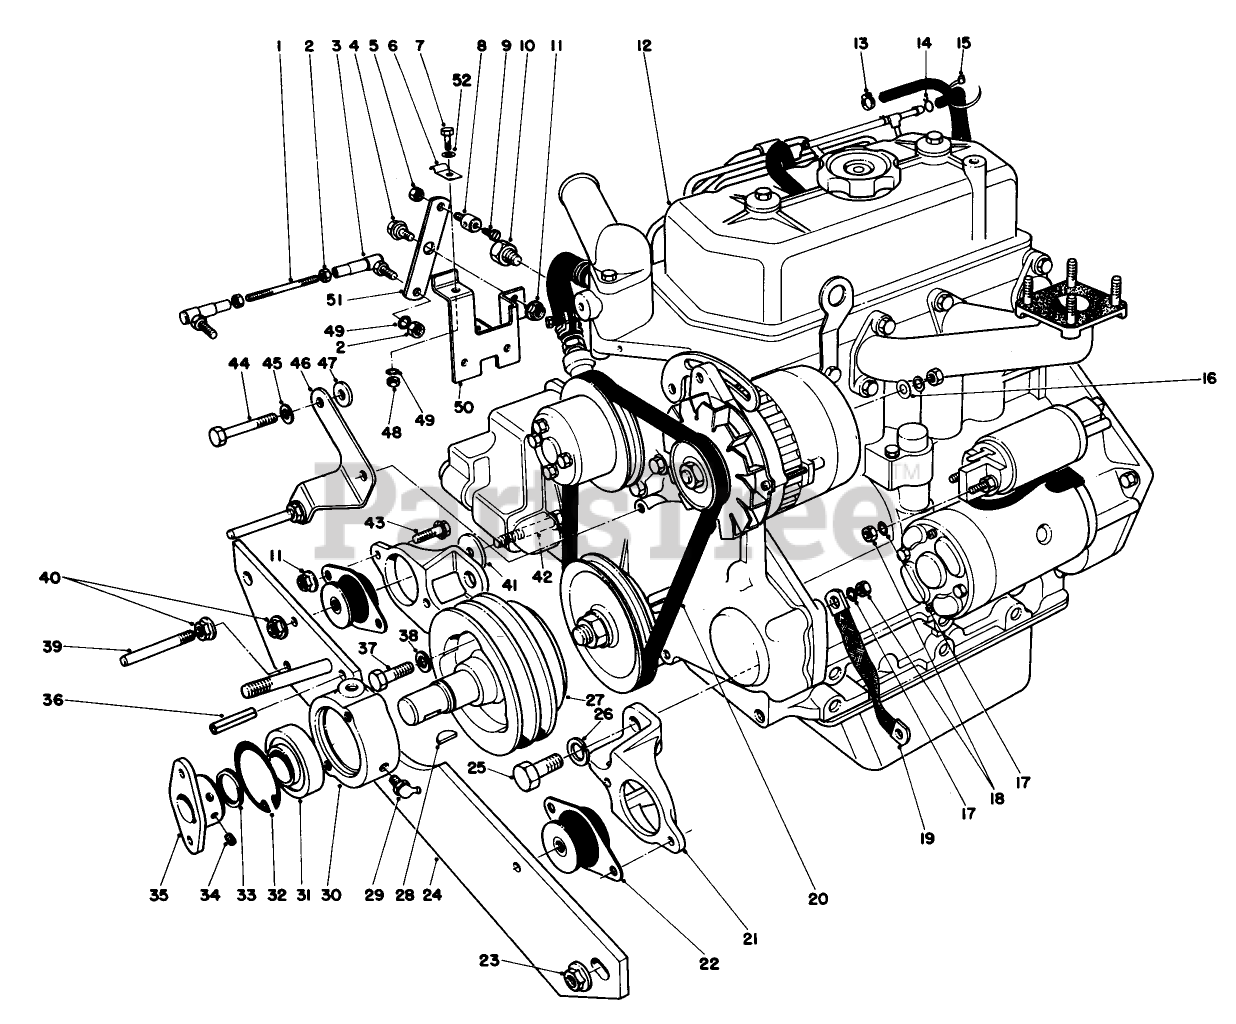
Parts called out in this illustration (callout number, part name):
1	THROTTLE LINK
2	NUT-HEX
3	BALL JOINT
4	BOLT-SHOULDER
5	NUT-LOCK, NI
6	CLAMP-BODEN
7	SCREW-HH
8	SWIVEL - CABLE
9	SCREW-HH
10	TEMP GAUGE ADAPTER
11	NUT-HF
12	Engine
13	CLAMP-HOSE
14	CLAMP-HOSE
15	TIE-CABLE
16	SPACER
17	WASHER-LOCK, INTERNAL
18	NUT-HEX
19	CABLE-GROUND
20	V-BELT, FAN
21	Engine Mount
22	Engine Mount Rubber
23	NUT-HF
24	FRT ENGINE SUPT WA
25	SCREW-HH
26	WASHER-LOCK, SPRING
27	ENGINE PULLEY
28	KEY-WOODRUFF
29	FITTING-GREASE
30	COLLAR-BEARING
31	Bearing
32	RING-SNAP, INTERNAL
33	RING-SNAP
34	SCREW-SET, HSH
35	HUB-ENGINE
36	PIN-ROLL
37	HEX HD CAPSCREW
38	WASHER-LOCK, SPRING
39	STUD-RETAINER, BELT
40	NUT-HHF, WHIZ
41	WASHER-TOP THRUST
42	SCREW-HH
43	SCREW-HHF
44	CAPSCREW-HH
45	WASHER-LOCK, SPRING
46	BELT GUIDE BRKT
47	WASHER-FLAT
48	NUT-HEX
49	WASHER-LOCK
50	Bracket Throttle Control
51	THROTTLE LEVER
52	WASHER-FLAT
